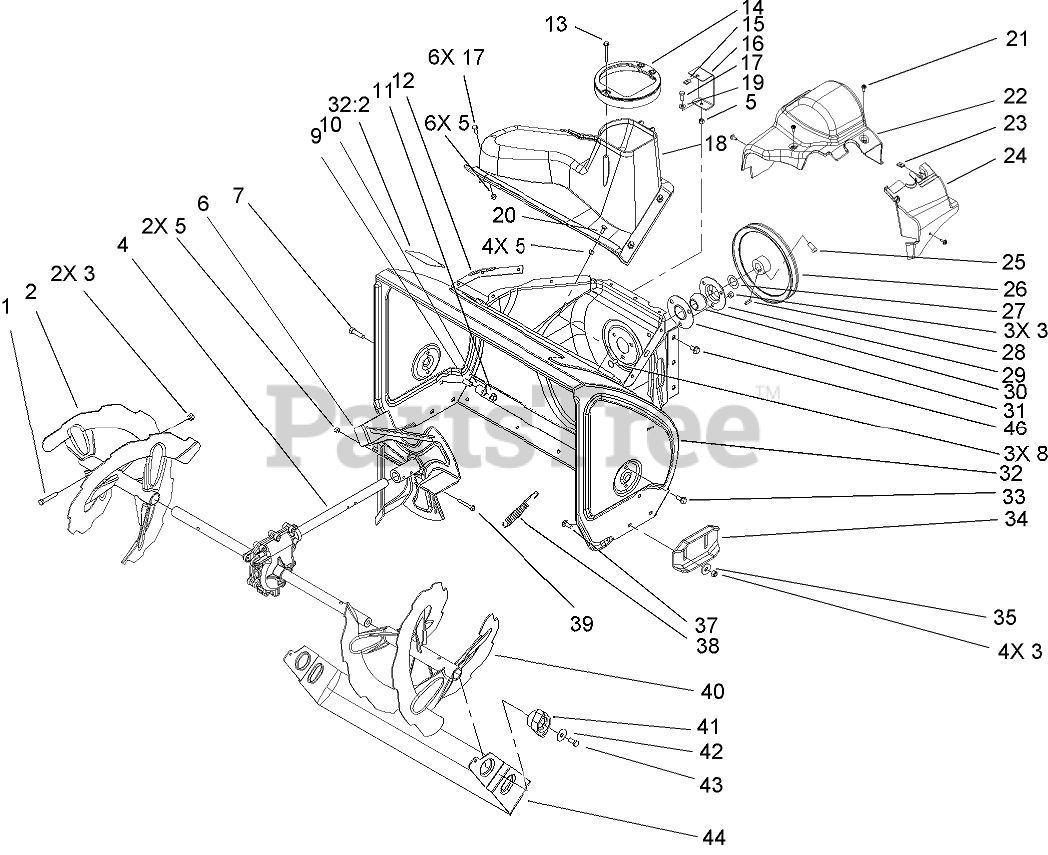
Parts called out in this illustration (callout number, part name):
1	SCREW-HH
2	RH AUGER ASM
3	NUT-LOCK, NI
4	AUGER GEARCASE ASM
5	NUT-LOCK, NI
6	IMPELLER ASM
7	SCREW-HH
8	SCREW-CARR
9	SPACER-SCRAPER, STOP
10	CUSHION-SCRAPER, STOP
11	NUT-HF
12	SEAL-FLANGE, COVER
13	SCREW-PLASTITE
14	GUIDE-CHUTE
15	NUT-SPEED, U-TYPE
16	BRACKET-COVER, CLIP NUT
17	SCREW-HH
18	COVER
19	WASHER-FLAT
20	BOLT-CARR
21	SCREW-HWH
22	COVER-BELT
23	NUT-SPEED
24	COVER-EXTENSION, BELT
25	SCREW-SET, SQH
26	PULLEY-IMPELLER
27	WASHER-THRUST
28	KEY-WOODRUFF
29	FLANGE-CUP, BEARING
30	BEARING-BALL
31	FLANGE-CUP, BEARING
32	HOUSING-AUGER, 28 INCH
32:2	DECAL-WARNING, AUGER
33	SCREW-HWHTF
35	WASHER
37	SCREW-CARR
38	SPRING-SCRAPER
39	SCREW-HHF
40	LH AUGER ASM
41	BEARING-AUGER
42	WASHER
43	SCREW-HH
44	SCRAPER-PIVOTING, 28 INCH
46	SCREW-HWHTF
